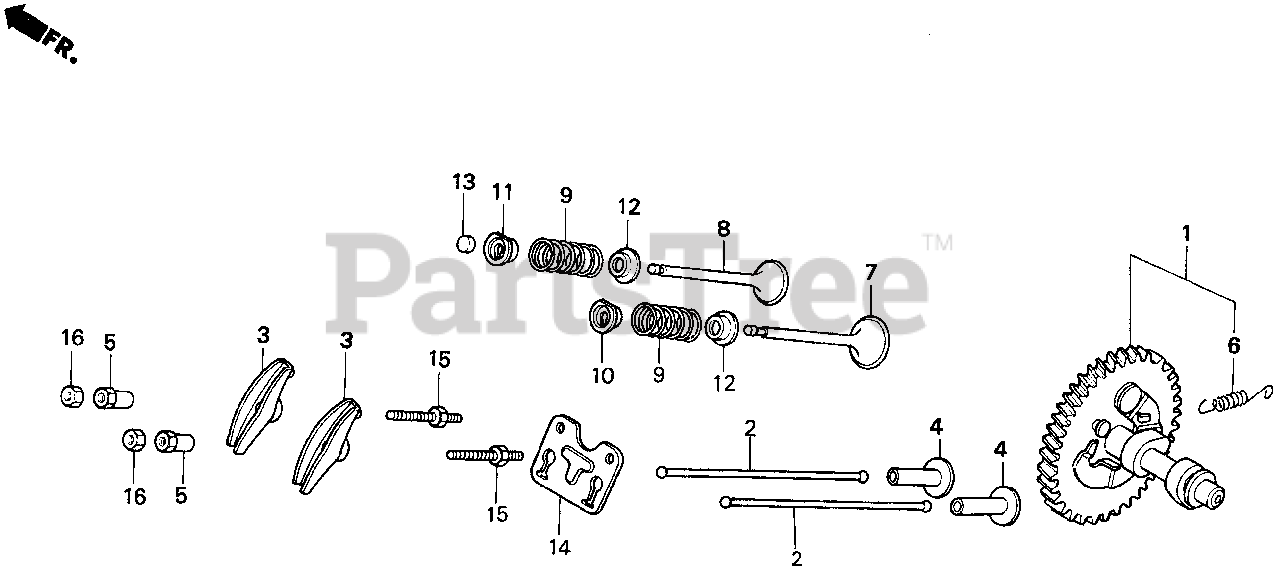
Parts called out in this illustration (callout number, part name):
1	CAMSHAFT ASSY.
2	ROD, PUSH
3	ARM, VALVE ROCKER
4	LIFTER, VALVE
5	PIVOT, ROCKER ARM
6	SPRING, WEIGHT RETURN
7	VALVE, IN.
8	VALVE, EX.
9	SPRING, VALVE
10	RETAINER, IN. VALVE SPRING
11	RETAINER, EX. VALVE SPRING
12	SEAT, VALVE SPRING
13	ROTATOR, VALVE
14	PLATE, PUSH ROD GUIDE
15	BOLT, PIVOT (8MM)
16	NUT, PIVOT ADJ.
